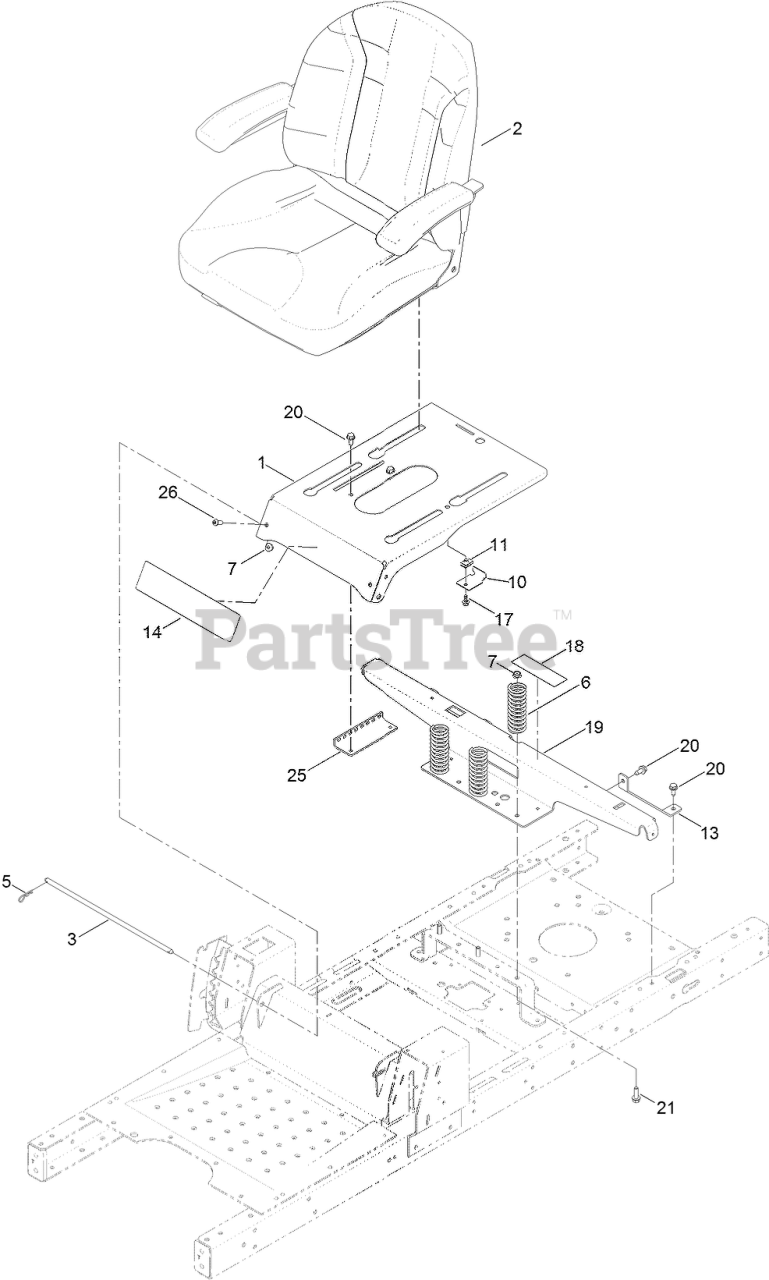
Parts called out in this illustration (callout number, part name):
1	PAN-SEAT, DELUXE
2	SEAT ASM
3	ROD-PIVOT, NARROW
5	PIN-COTTER
6	SPRING-COMPRESSION
7	NUT-HF, NI
10	BRACKET-STOP, SEAT
13	SUPPORT-TANK, REAR
14	DECAL-TIMECUTTER
17	SCREW-HHF
18	DECAL-SERVICE, CE
19	SUPPORT-POD
20	SCREW-HWHTF
21	SCREW-HHF
25	BRACKET-LATCH, SEAT
26	SCREW-HSBH
